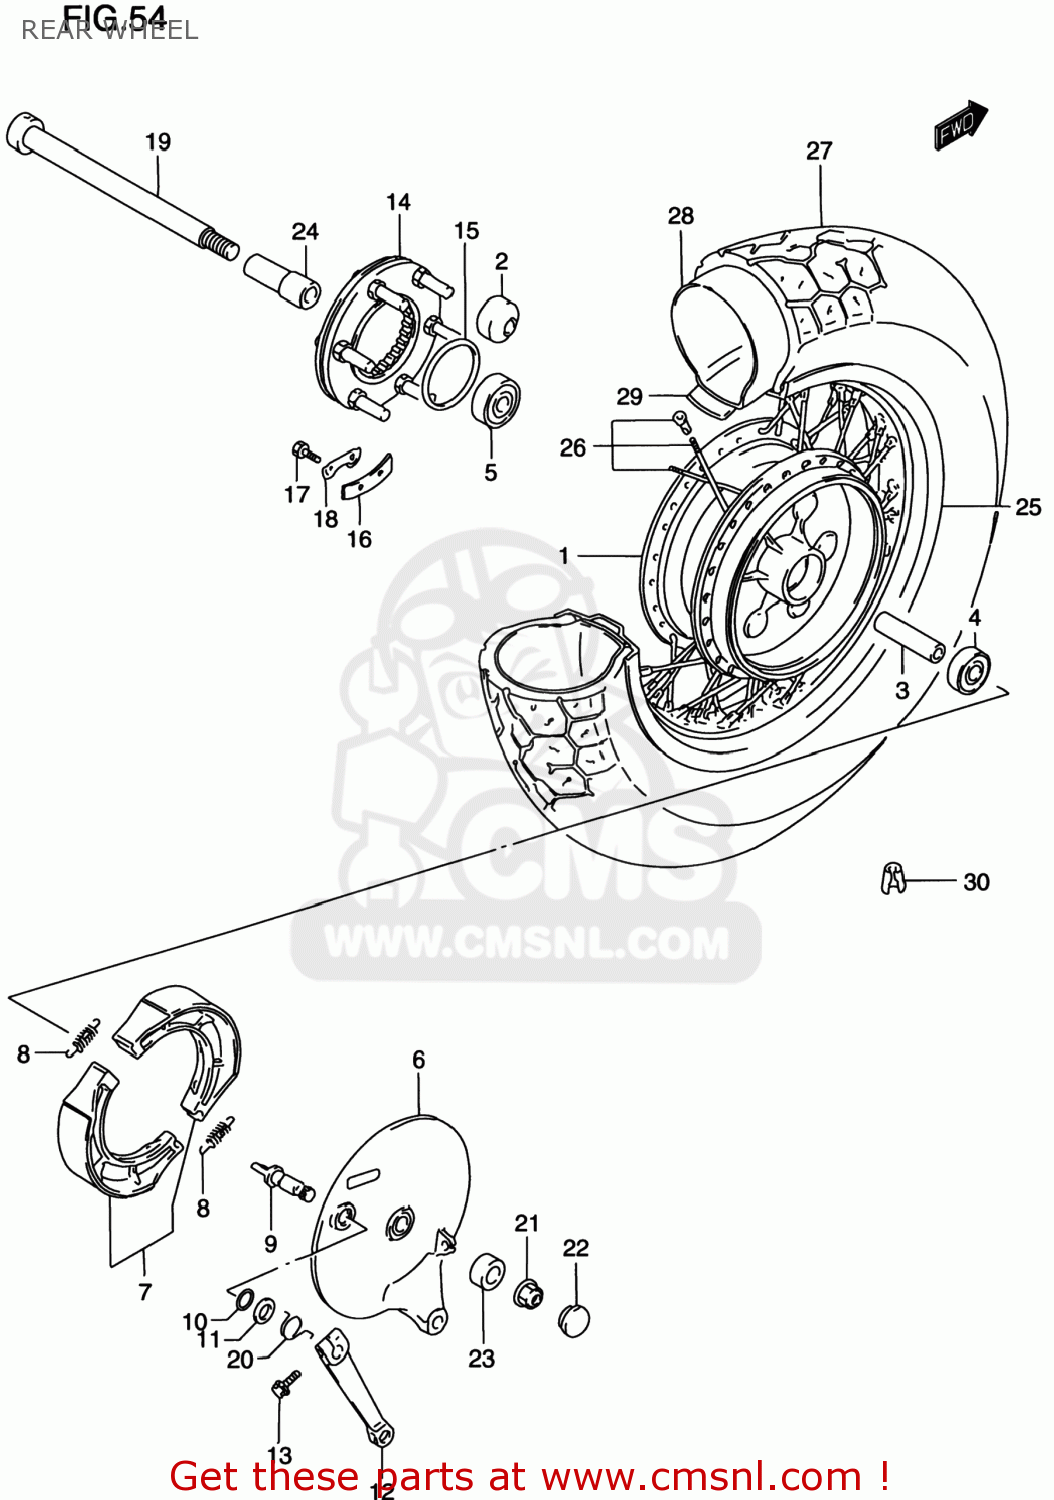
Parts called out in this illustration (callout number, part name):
1	HUB SET,RR
2	BUSH
3	SPACER(17.5X25X80)
4	BEARING
5	BEARING
6	PANEL,RR BRAKE ANCHOR
7	SHOE SET,BRAKE (NAS)
8	SPRING,BRAKE SHOE
9	CAM,RR BRAKE
10	O RING(D:2.4,ID:14.8)
11	WASHER(15.5X24X1.6)
12	LEVER,RR BRAKE CAM
13	BOLT
14	JOINT ASSY,RR HUB DRIVEN
15	O RING(D:2.1,ID:65)
16	WASHER,THRUST(T:1.6)
17	BOLT(6X16)
18	WASHER
19	AXLE,RR
20	SPRING
21	NUT
22	CAP,RR AXLE,R
23	SPACER,RR AXLE,L
24	SPACER,RR AXLE,L
25	RIM,RR WHEEL MT(3.00X15 M/C)
26	SPOKE ASSY,RR WHEEL
27	TIRE,REAR 140/90-15M/C
28	TUBE ASSEMBLY,WHEEL,INNER
29	PROTECTOR,WHL INR TUBE
30	BALANCER,WHEEL
